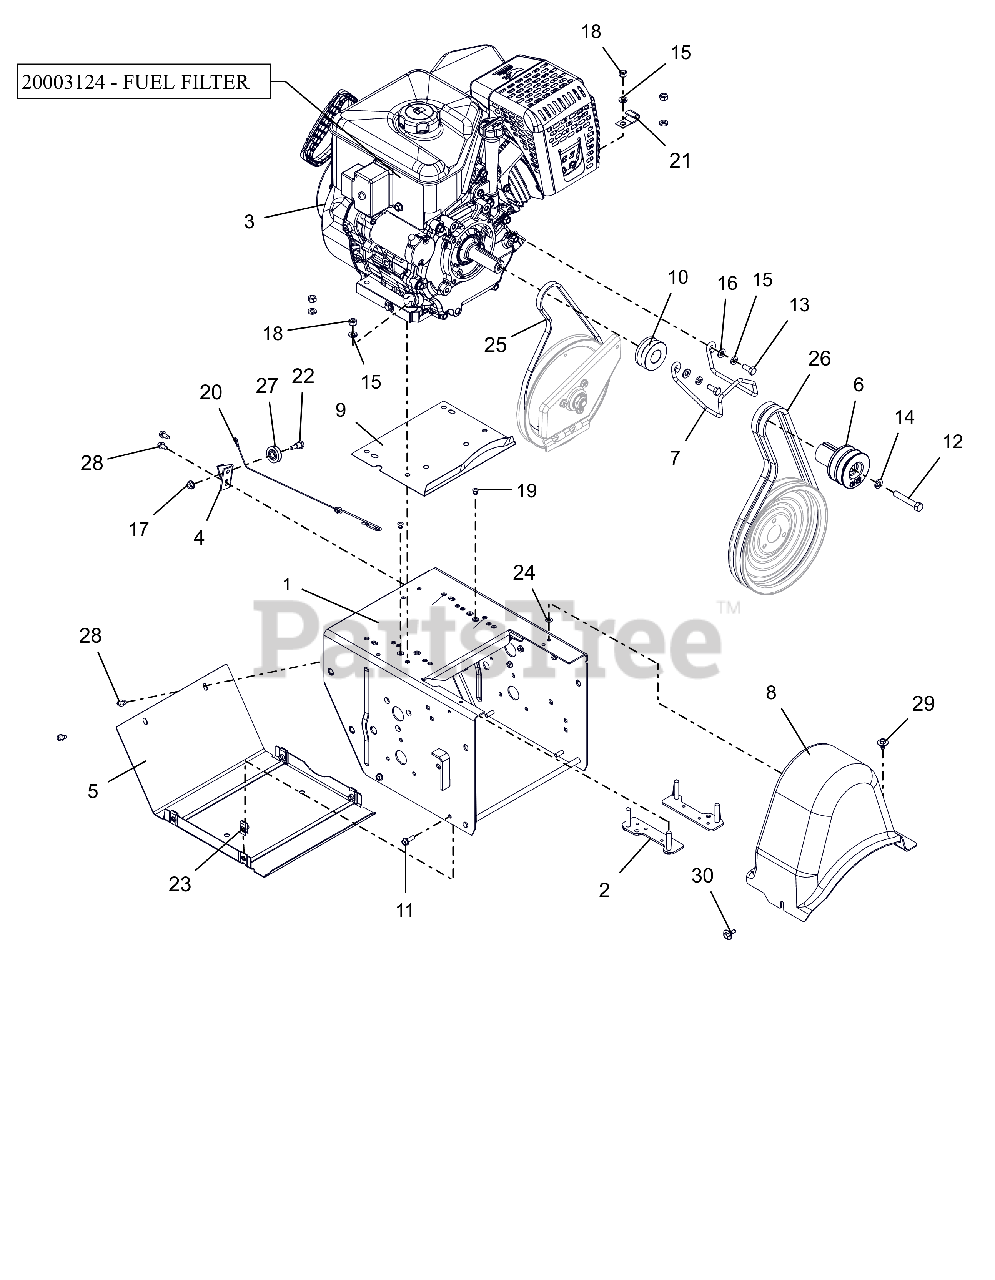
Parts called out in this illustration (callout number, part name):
1	FRAME, MAIN-DELUXE(WELDMENT)
2	STRAP, BOLT-LARGE
3	ENGINE, EFI 369 GEN 3 240V/60W
3	FILTER, FUEL - IN-LINE EFI
4	BRACKET, CABLE PULLEY
5	COVER, BOTTOM
6	SHEAVE,ATTACHMENT-SHO 2 GRV
7	FINGER, BELT
8	COVER, BELT-LARGE
9	BAFFLE, WATER - LARGE BLOCK
10	SHEAVE, TRACTION (KEYLESS)
11	BLT, HWH .25-20X.75 G5 ZCC
12	BLT, HEX .38-24X2.25 G5 ZCC
13	BLT, HEX .31-24X.750 G5 ZCC
14	WSHR,LK-REG .375X.094 ZCC
15	WSHR, LK-HVY .312X.097 ZCC
16	WSHR,FLT .344X.688X.065 ZCC
17	NUT-LK-TOP-FLG .250-20 GF ZCC
18	NUT, HEX .312-18 ZCC
19	RVT, POP .1875 ZCC
20	CABLE, LOWER TRACTION,SS & PRO
21	J-CLAMP
22	BOLT, SHLDR -.375 X .375 X .25-20
23	NUT-RTNR .25-20X.56
24	NUT-PUSH .25X.50 O.D.
25	V-BELT, 3L-WRAPPED
26	V-BELT, HA-RAW EDGE (SET)
27	PULLEY, CABLE
28	SCR-TAP .25-20X.50 HWH ZCC
29	SCR, TAP .25-20X.50 LG HWH ZCC
30	SCR-TAP .25-20X.5 CAPTIVE
